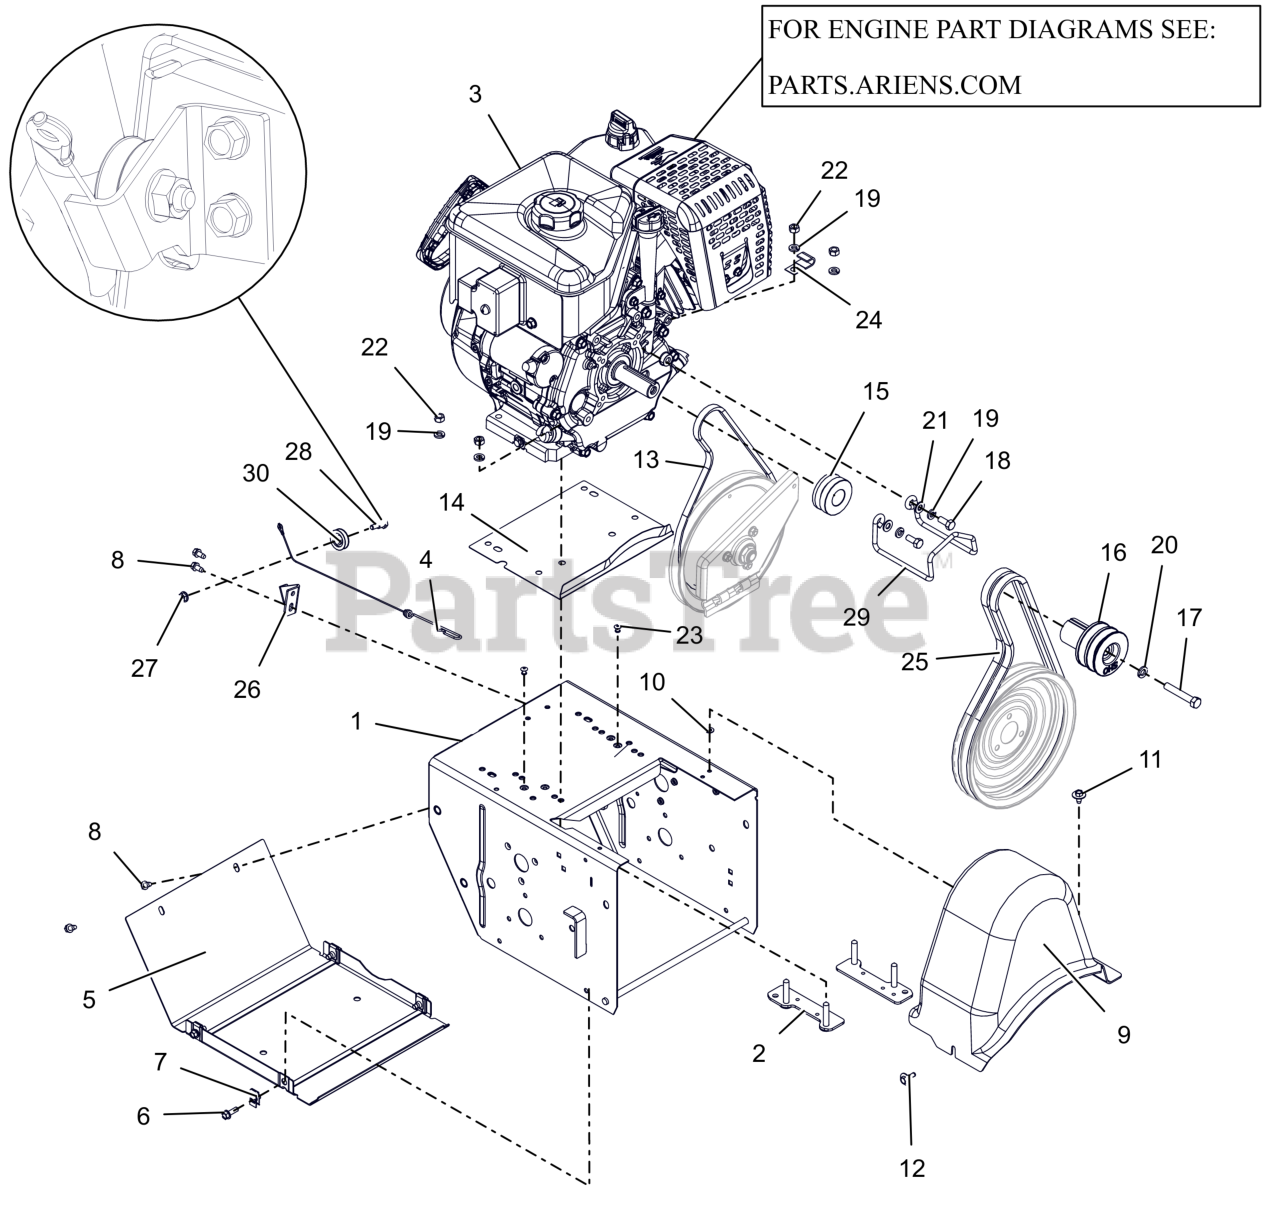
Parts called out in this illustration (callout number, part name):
1	FRAME, MAIN - 14GA DELUXE (ORANGE)
2	STRAP, ENGINE-MEDIUM BLOCK
3	ENGINE, AX306 GEN3 240V60W
4	CABLE, LOWER TRACTION,SS & PRO
5	COVER, BOTTOM
6	BLT, HWH .25-20X.75 G5 ZCC
7	NUT-RTNR .25-20X.56
8	SCR-TAP .25-20X.50 HWH ZCC
9	COVER, BELT-LARGE
10	NUT-PUSH .25X.50 O.D.
11	SCR, TAP .25-20X.50 LG HWH ZCC
12	SCR-TAP .25-20X.5 CAPTIVE
13	V-BELT, 3L-WRAPPED
14	BAFFLE, WATER - LARGE BLOCK
15	SHEAVE, TRACTION (KEYLESS)
16	SHEAVE,ATTACHMENT-SHO 2 GRV
17	BLT, HEX .38-24X2.25 G5 ZCC
18	BLT, HEX .31-24X.750 G5 ZCC
19	WSHR, LK-HVY .312X.097 ZCC
20	WSHR,LK-REG .375X.094 ZCC
21	WSHR,FLT .344X.688X.065 ZCC
22	NUT, HEX .312-18 ZCC
23	RVT, POP .1875 ZCC
24	J-CLAMP
25	V-BELT, HA-RAW EDGE (SET)
26	BRACKET, CABLE PULLEY
27	NUT-LK-TOP-FLG .250-20 GF ZCC
28	BOLT, SHLDR -.375 X .375 X .25-20
29	FINGER, BELT
30	PULLEY, CABLE
